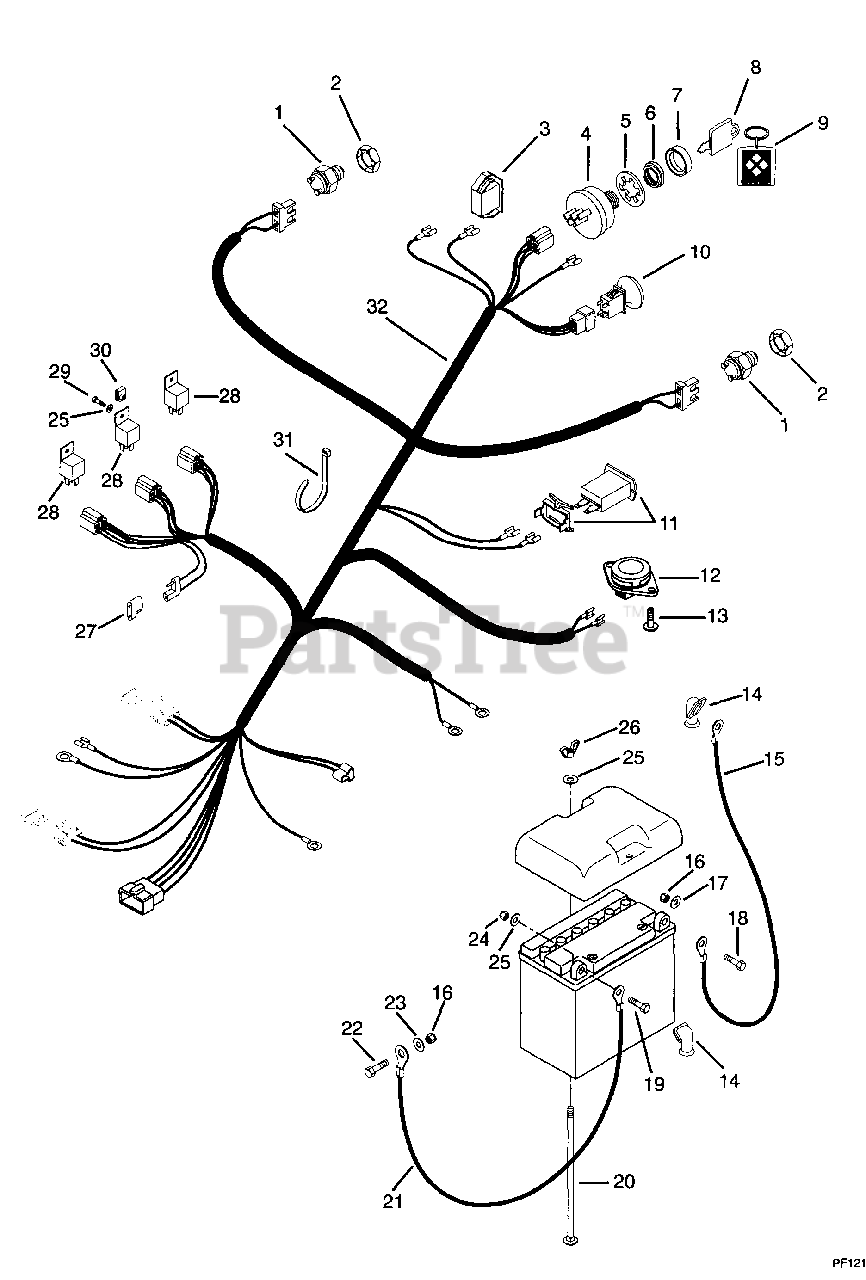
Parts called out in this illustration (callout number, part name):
1	Switch-Neutral Start N.O.
2	Nut-Stamped .56-18
3	Light, Indicator
4	Key Switch
5	Washer-Locking-Internal .563 x .040
6	Nut-Panel .562-24
7	Cap-Ignition Switch
8	Ignition Switch Key
9	Key Chain
10	Mount Plate, Transaxle Right Hand
11	Hour Meter
12	Switch-Seat
13	Screw-Machine .25-20 x .50
14	Boot, Insulator
15	Start Cable 22"
16	Nut-Locking-Nylon .312-18 Grade 2
17	Washer-Flat-Steel .344 x .688 x .065
18	Bolt-Hex .31-18 x 1.00 Grade 5
19	Bolt-Hex .25-20 x .75 Grade 5
20	Bolt-Round Head Square Neck .35-20 x 7.00
21	Cable, Negative Battery
22	Bolt-Hex .312-18 x .750
23	Washer-Flat-Steel .312 x .734 x .065
24	Nut-Locking-Nylon .250-20 Grade 2
25	Washer-Flat-Steel .281 x .620 x .065
26	Nut-Wing .250-20
27	Molded Diode Plug
28	Relay
29	Bolt-Hex .25-20 x .75 Grade 5
30	Nut-Retainer .25-20 x .56
31	Tie Wrap, Black
32	Harness, Wiring 18 HP Kohler
